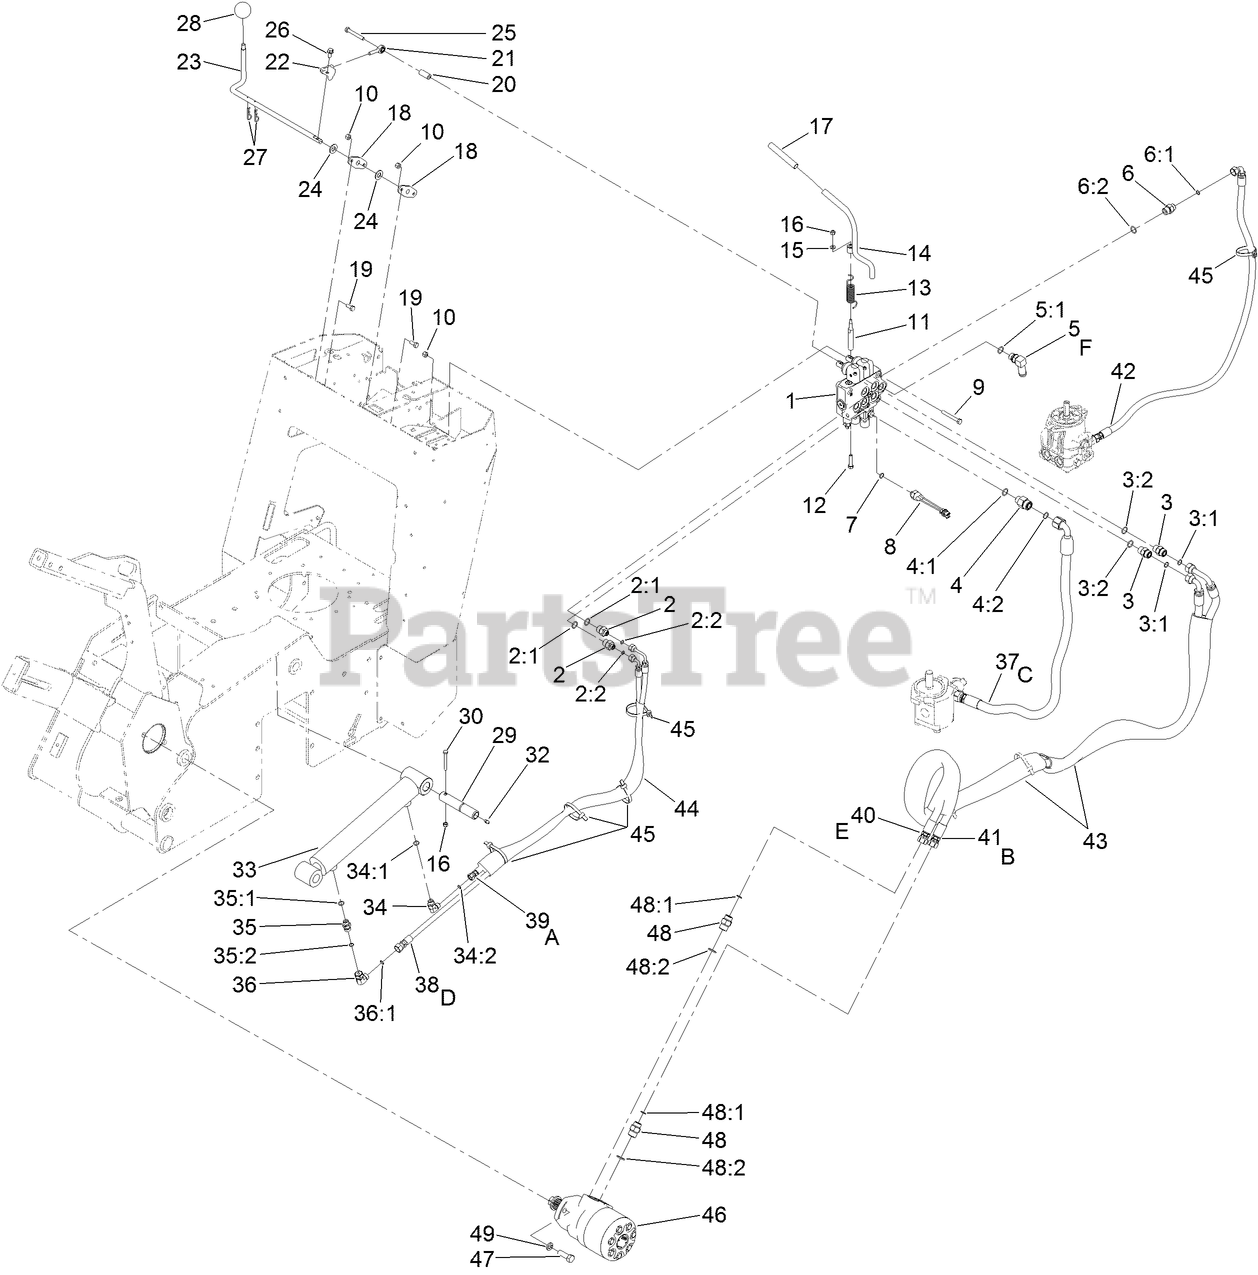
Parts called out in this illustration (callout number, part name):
1	HYD VALVE ASM
2	FITTING-STR
2:1	O-RING
2:2	O-RING
3	FITTING-STRAIGHT
3:1	O-RING
3:2	O-RING
4	FITTING-STRAIGHT
4:1	O-RING
4:2	O-RING
5	FITTING-ELBOW, 90
5:1	O-RING
6	FITTING-STRAIGHT
6:1	O-RING
6:2	O-RING
7	O-RING
8	SWITCH-BALL
9	SCREW-HH
10	NUT-LOCK, NI
11	SPACER-HIFLO
12	SCREW-HH
13	SPRING-TORSION
14	LEVER-AUXILIARY
15	WASHER-FLAT
16	NUT-LOCK, NI
17	GRIP-RUBBER
18	BEARING-WHEEL, FRICTION
19	SCREW-HH
20	SPACER
21	BEARING-ROD END
22	BRACKET-CONTROL
23	ROD-LEVER, CYLINDER
24	WASHER-FLAT
25	SCREW-HH
26	SCREW-HHF
27	PIN-HAIR
29	PIN-PIVOT
30	SCREW-HH
32	FITTING-GREASE
33	HYD CYLINDER ASM
34	FITTING-ELBOW, 90 DEG
34:1	O-RING
34:2	O-RING
35	VALVE-CHECK
35:1	O-RING
35:2	O-RING
36	FITTING-HYD, 90 DEG
36:1	O-RING
37	HOSE-HYD
38	HOSE-HYD
39	HOSE-HYD
40	HOSE-HYD
41	HOSE-HYD
42	HOSE-HYD
43	SLEEVE-PROTECTIVE
44	SLEEVE-PROTECTIVE
45	TIE-CABLE
46	HYD MOTOR ASM
47	SCREW-HH
48	FITTING-STRAIGHT
48:1	O-RING
48:2	O-RING
49	SCREW-HH
